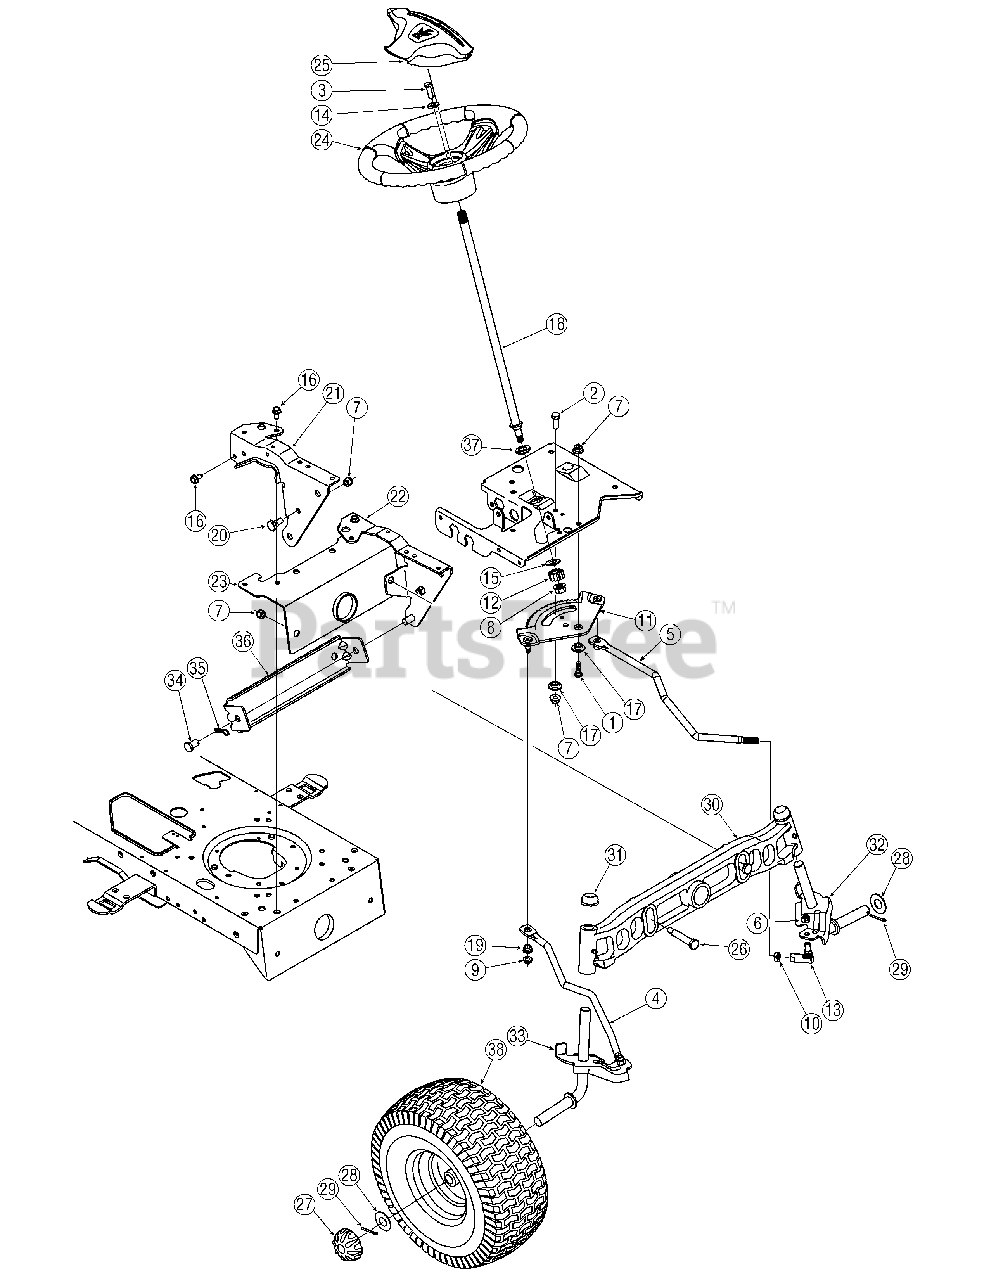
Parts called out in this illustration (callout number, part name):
1	Hex Screw, 3/8-16, 1.00, Gr5
2	Hex Screw, 3/8-16, 1.00, Gr5
3	Hex Screw, 5/16-18, 1.00, Gr5
4	Link, Drag, RH
5	Link, Drag, LH
6	Nut, Hex Lock, 3/8-24
7	Nut, Flange Lock, 3/8-16, Grf
8	Nut, Flange Lock, 7/16-20
9	Nut, Flange Lock, 5/16-18, Gr5
10	Nut, Jam, 7/16-20, Gr2
11	Gear, Steering, 11/90 Ratio
12	Gear, Pinion, Steering
13	Ball Joint, 7/16-20, Lock
14	Washer, Flat, .406 x .875 x .105
15	Washer, Flat, .51 x 1.12 x .06
16	Screw, 5/16-18, 0.750
17	Spacer, Shoulder, .38 x 1.00 x .31
18	Shaft, Steering, .625 OD x 24.25
19	Plastic Bushing .380 ID
20	Screw, Shoulder, .498 x .340
24	Steering Wheel, 13.25
25	Steering Wheel Cover
26	Shoulder Screw, .5 x 2.2, 3/8-16
27	Deluxe Hub Cap
28	Flat Washer, .78 x 1.589 x .06
29	Cotter Pin, 5/32 x 1.25
30	Cast Iron Pivot Bar
32	LH Axle Assembly, .750
33	RH Axle Assembly, .750
34	Pin, Clevis, .50 x .78
35	Cotter Pin, Internal, .080 x 1.5625
37	Hex Flange Bearing
